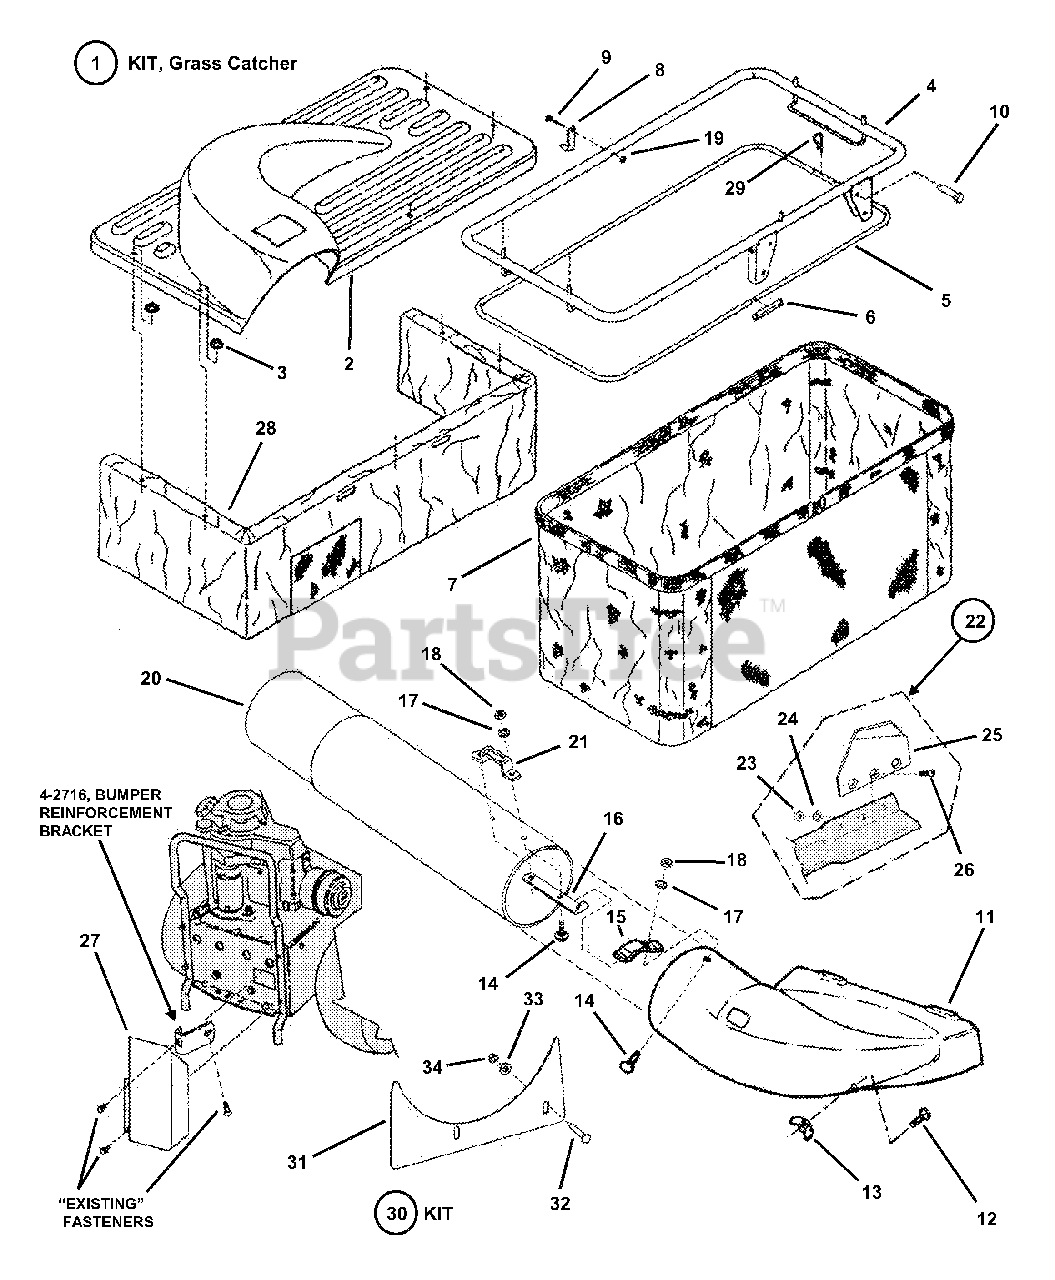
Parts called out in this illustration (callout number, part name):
1	KIT, Grass Catcher (26" & 30" Models)
2	TOP, Container
3	WASHER, Faceted
4	FRAME, Weldment
5	ROD, Bag
6	CONNECTOR, Bag Rod
7	BAG, Grass
8	LATCH, Top
9	SCREW, #10-32 x 1-3/8" Hex Head Machine
10	PIN, 5/16 x 1-11/16" Clevis
11	ADAPTER, DecK
12	BOLT, 5/16-18 x 1" Short Neck Carriage, Grade 5
13	NUT, 5/16-18 Wing
14	BOLT, 1/4-20 x 3/4" Short Neck Carriage, Grade 5
15	LATCH, Tube
16	BASE, Handle
17	WASHER, 1/4 Internal Tooth Lock
18	NUT, 1/4-20 Hex
19	NUT, #10-32 Hex Lock
20	TUBE, Grass (36" long)
21	HANDLE, Tube
22	KIT, Air Lift
23	NUT, 5/16-24 Hex
24	WASHER, 5/16" Internal Tooth Lock
25	AIR-LIFT
26	SCREW, 5-16-24 x 11/16" Machine
27	SHIELD, Muffler Heat (8 HP Engines)
28	DUST SKIRT
29	PIN, 3/32 x 1-1/2" Hair
30	KIT, Catcher Debris Shield
31	SHIELD, Debris
32	BOLT, 1/4-20 x 1-1/2" Hex
33	WASHER, 1/4" Flat
34	NUT, 1/4-20 Hex Top Lock
